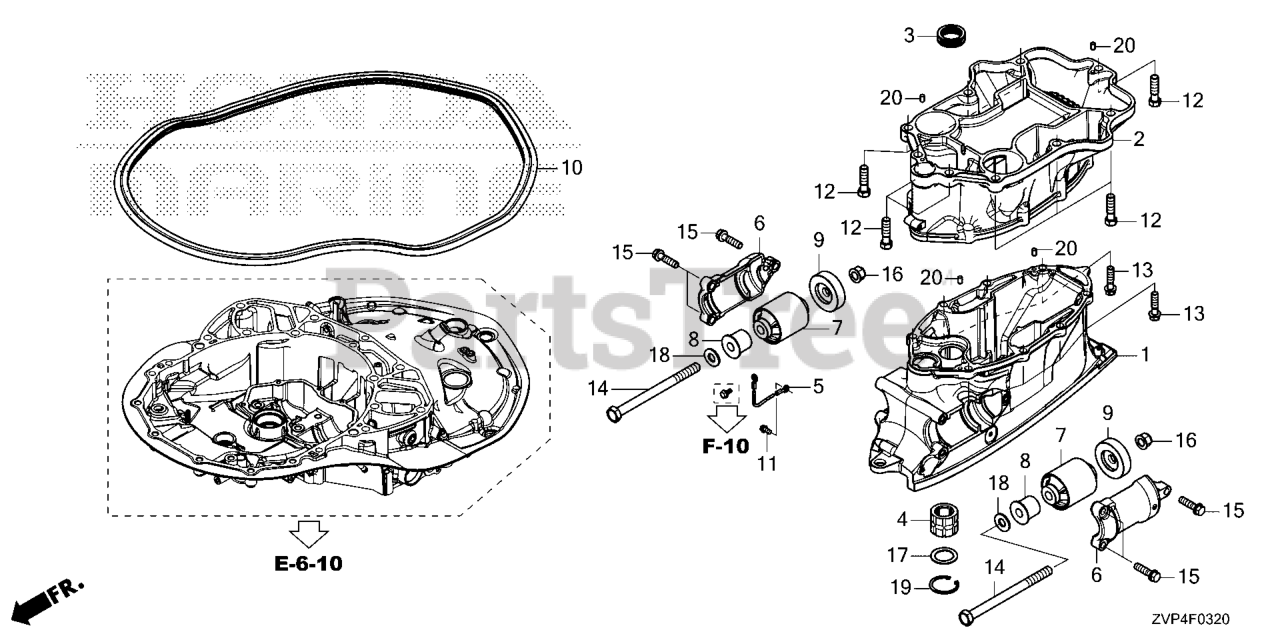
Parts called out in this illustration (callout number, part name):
1	CASE, EXTENSION
2	SEPARATOR, EXTENSION
3	GROM, EXTENSION CASE
4	BUSH, VERTICAL SHAFT
5	WIRE, LEAD (1.5X116MM)
6	HSG, MT (LOWER)
7	MOUNT COMP, RUBBER
8	COLR, MOUNT (LOWER)
9	STOPPER, MOUNT
10	SEAL, MOUNT CASE
11	BOLT, FLANGE (6X12) Use from Frame SN 1005249.
12	BOLT-WASHER (12X50)
13	BOLT-WASHER (10X37)
14	BOLT, HEX. (14X185)
15	BOLT-WASHER (10X40)
16	NUT (14MM)
17	WASHER (30MM)
18	WASHER, PLAIN (14MM)
19	CIRCLIP (INNER) (43)
20	PIN, DOWEL (6X10)
